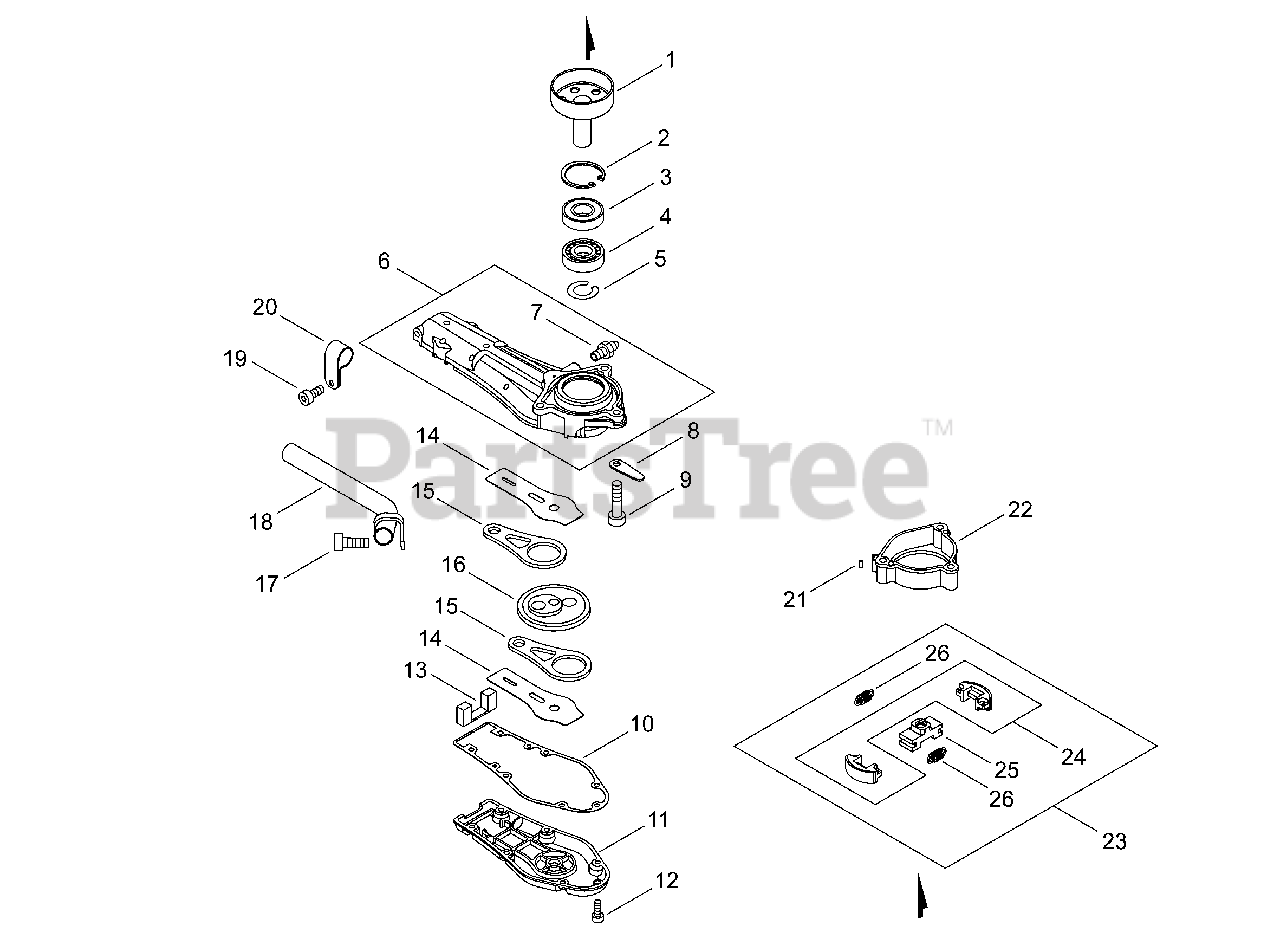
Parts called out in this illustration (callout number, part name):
1	DRUM, CLUTCH
2	CIRCLIP 35
3	BEARING, BALL 6202
4	BEARING, BALL 6202
5	CIRCLIP 14
6	CASE,GEAR
7	NIPPLE, GREASE
8	PIECE, PLATE
9	BOLT, TORX 6
10	GASKET,GEAR CASE
11	LID,GEARCASE
12	BOLT, TORX 4
14	PLATE,EYE
15	ROD, CONNECTING
16	GEAR,SPUR
17	BOLT, TORX 5
18	GUIDE, EXHAUST
19	BOLT, TORX 4
20	STAY, MUFFLER
21	NUT
22	CASE,CLUTCH
23	CLUTCH ASY
24	CLUTCH SHOE SET
25	HUB, CLUTCH
26	SPRING, CLUTCH
